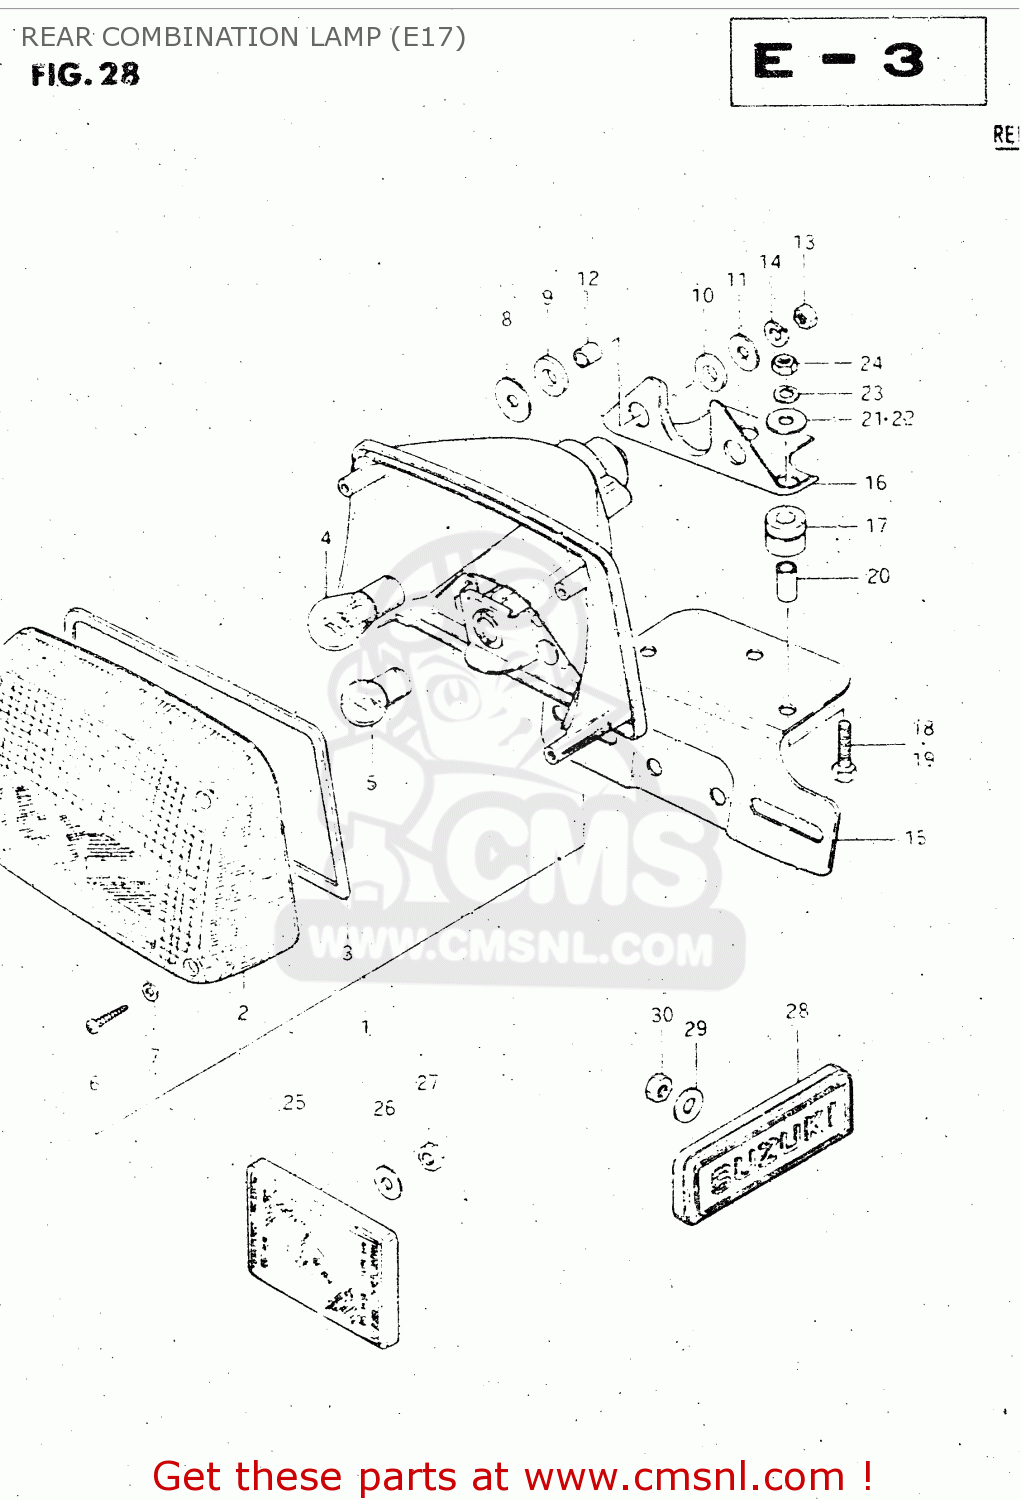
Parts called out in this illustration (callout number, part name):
1	LAMP ASSY, REAR COMBINATION
2	LENS
3	GASKET (NAS)
4	BULB 12V21/5W
5	BULB
6	SCREW
7	GASKET (NAS)
8	WASHER
9	CUSHION
10	CUSHION
11	WASHER(6,5X22X1.6)
12	SPACER(6.1X9X7.5)
13	NUT
14	LOCK WASHER
15	BRACKET, LICENCE PLATE
16	BRACKET,LICENSE PLATE
17	CUSHION, BRACKET
18	BOLT
19	BOLT
20	SPACER (6.4X9X15.5)
21	WASHER
22	WASHER
23	LOCK WASHER
24	NUT
25	REFLEX REFLECTOR,RR
26	WASHER(5.2X16X1)
27	NUT
28	EMBLEM, REAR SIDE
29	WASHER
30	NUT
